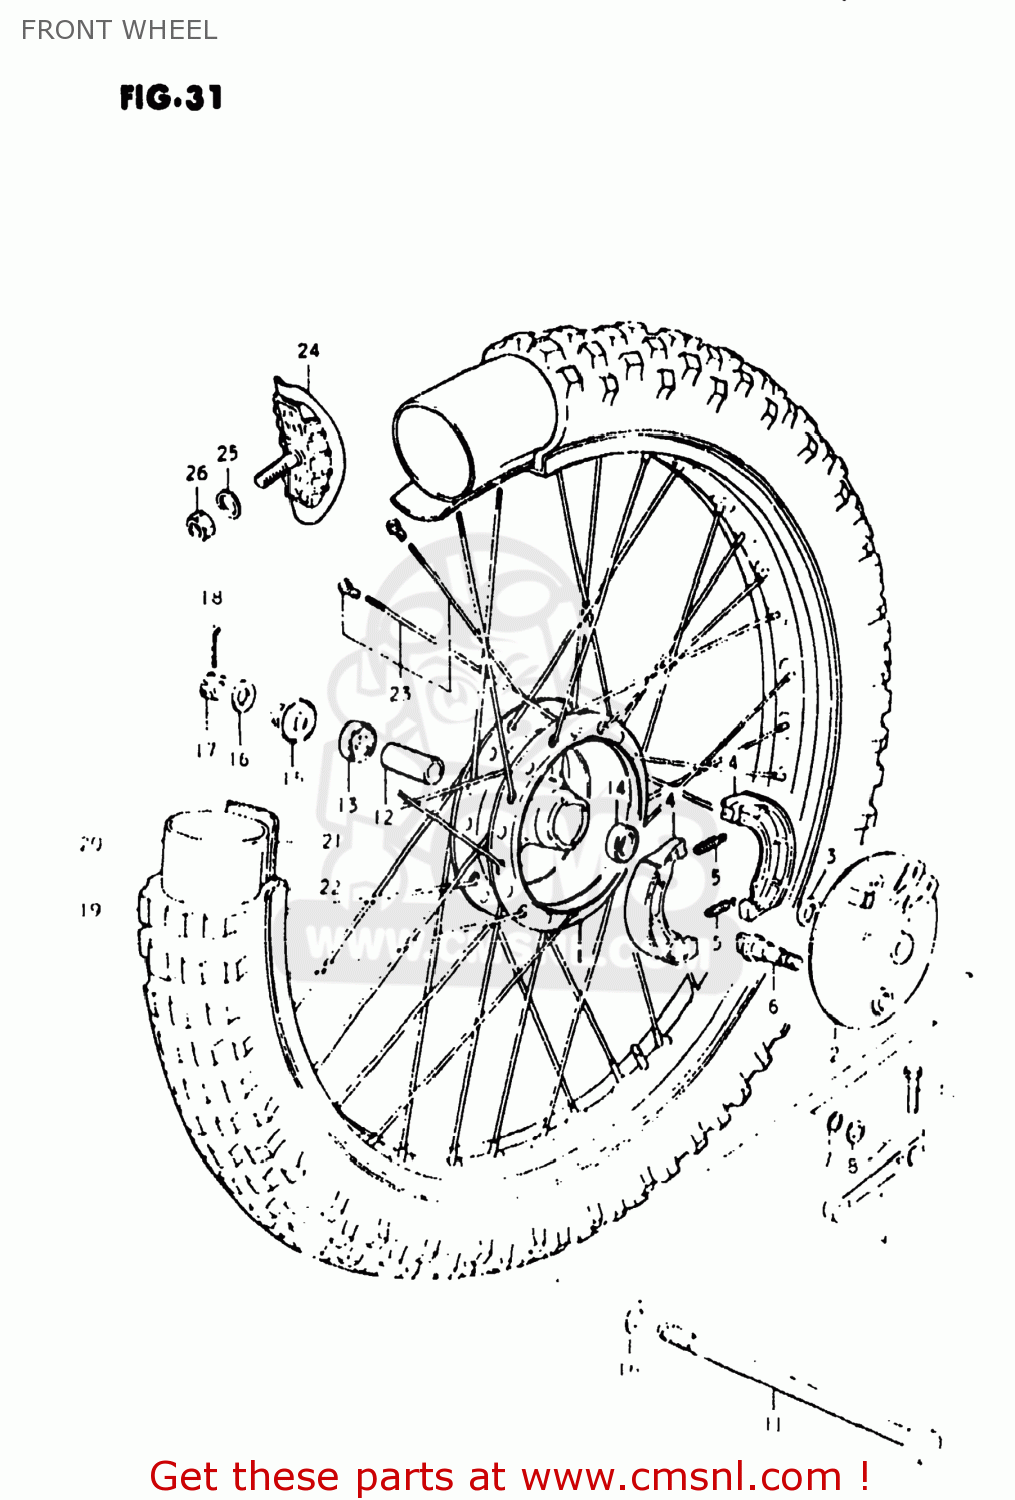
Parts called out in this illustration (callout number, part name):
1	HUB,FRONT
2	PANEL,FRONT HUB
3	BOSS
4	SHOE,BRAKE
5	SPRING(L:34)
6	CAM,FRONT BRAKE
7	O RING(D:2.5,ID:11.4)
8	WASHER(12.5X20X1)
9	LEVER,FRONT BRAKE CAM
10	BOLT
11	AXLE,FRONT
12	SPACER (12.6X19X52)
13	BEARING, RH
14	BEARING, RH
15	SPACER,FRONT AXLE,RIGHT
16	WASHER
17	NUT, REAR AXLE
18	COTTER PIN
19	TIRE,FRONT
20	TUBE
21	PROTECTOR,WHEEL,INNER
22	RIM,FRONT WHEEL
23	SPOKE SET,FRONT
24	STOPPER,BEAD
25	WASHER
26	NUT
